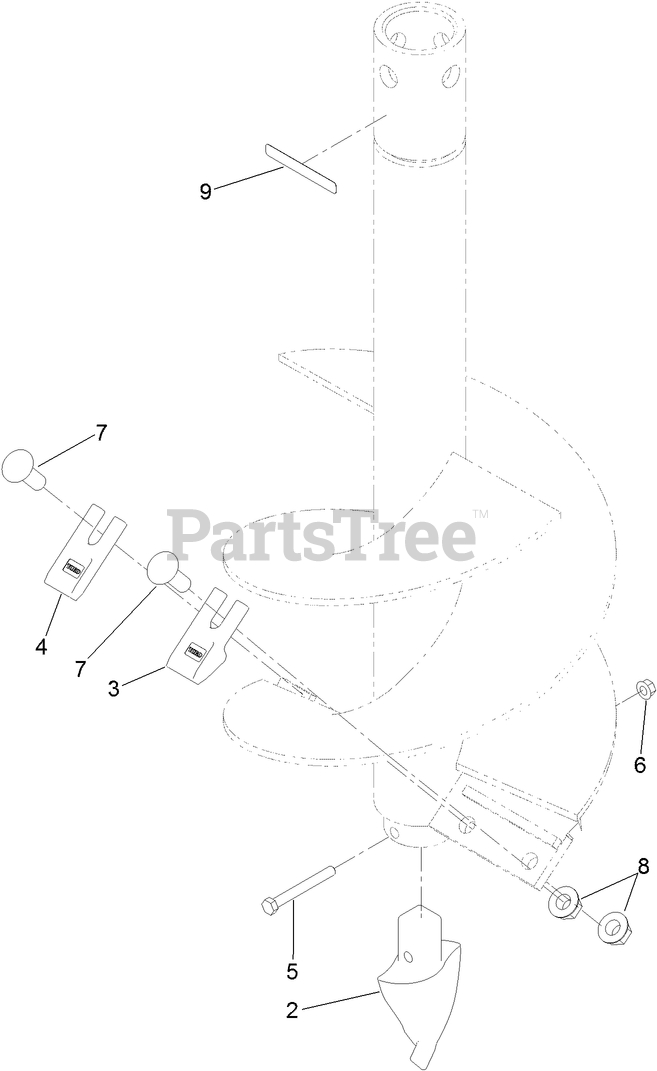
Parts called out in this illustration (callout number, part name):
2	PILOT-AUGER
3	TOOTH-OUTER
4	TOOTH-INNER
5	SCREW-HH
6	NUT-HF
7	SCREW-CARR
8	NUT-FLANGE
9	DECAL-WARNING
